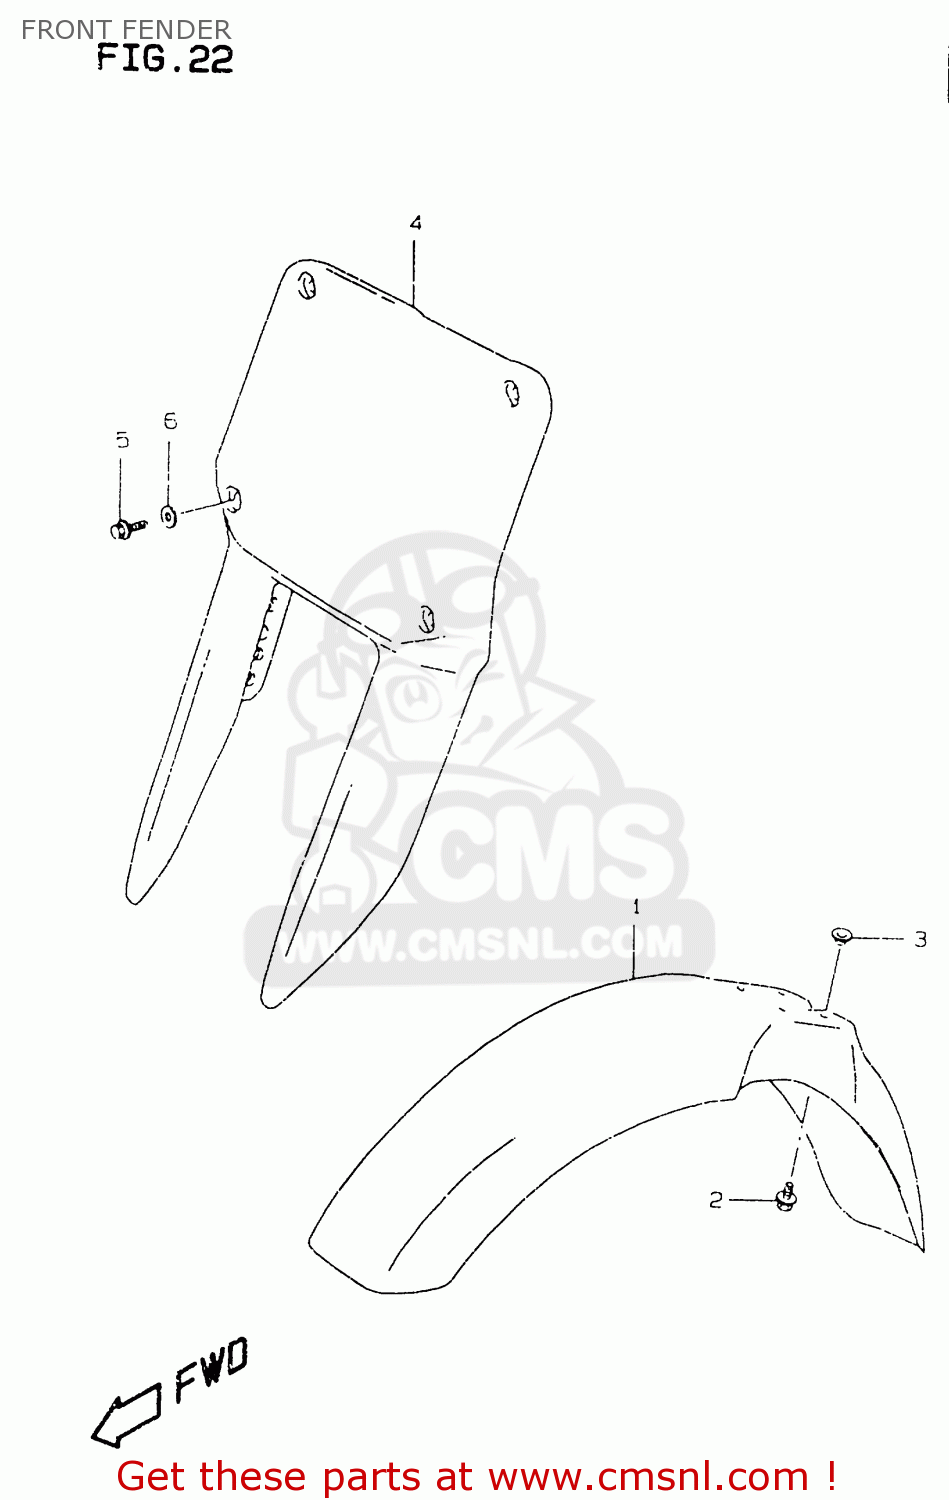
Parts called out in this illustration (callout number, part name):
1	FENDER,FRONT
2	BOLT(6X16)
3	WASHER
4	PLATE,NUMBER FR
5	BOLT
6	WASHER
